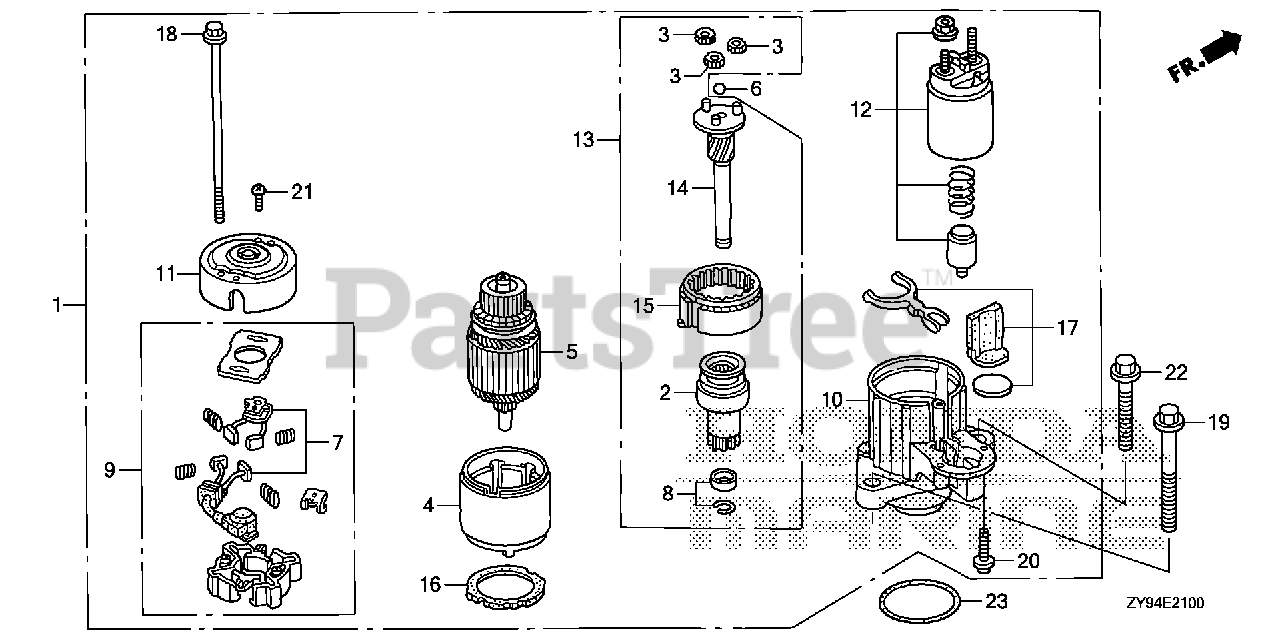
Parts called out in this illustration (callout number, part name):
1	STARTER MOTOR ASSY.
2	CLUTCH, OVERRUNNING
3	GEAR ASSY., PLANETARY
6	BALL, STEEL
8	STOPPER SET, SLEEVE
9	HOLDER, BRUSH
10	BRACKET, FR.
11	BRACKET, RR.
12	SWITCH ASSY., MAGNET
13	SHAFT ASSY., CLUTCH
14	SHAFT ASSY., GEAR
15	GEAR ASSY. (INNER)
18	BOLT A, THROUGH
19	BOLT, FLANGE (10X75)
20	SCREW, PAN (6X22) (SPECIAL)
21	SCREW, PAN (5X8)
22	BOLT, FLANGE (10X35)
23	O-RING (59.4X3.1)
